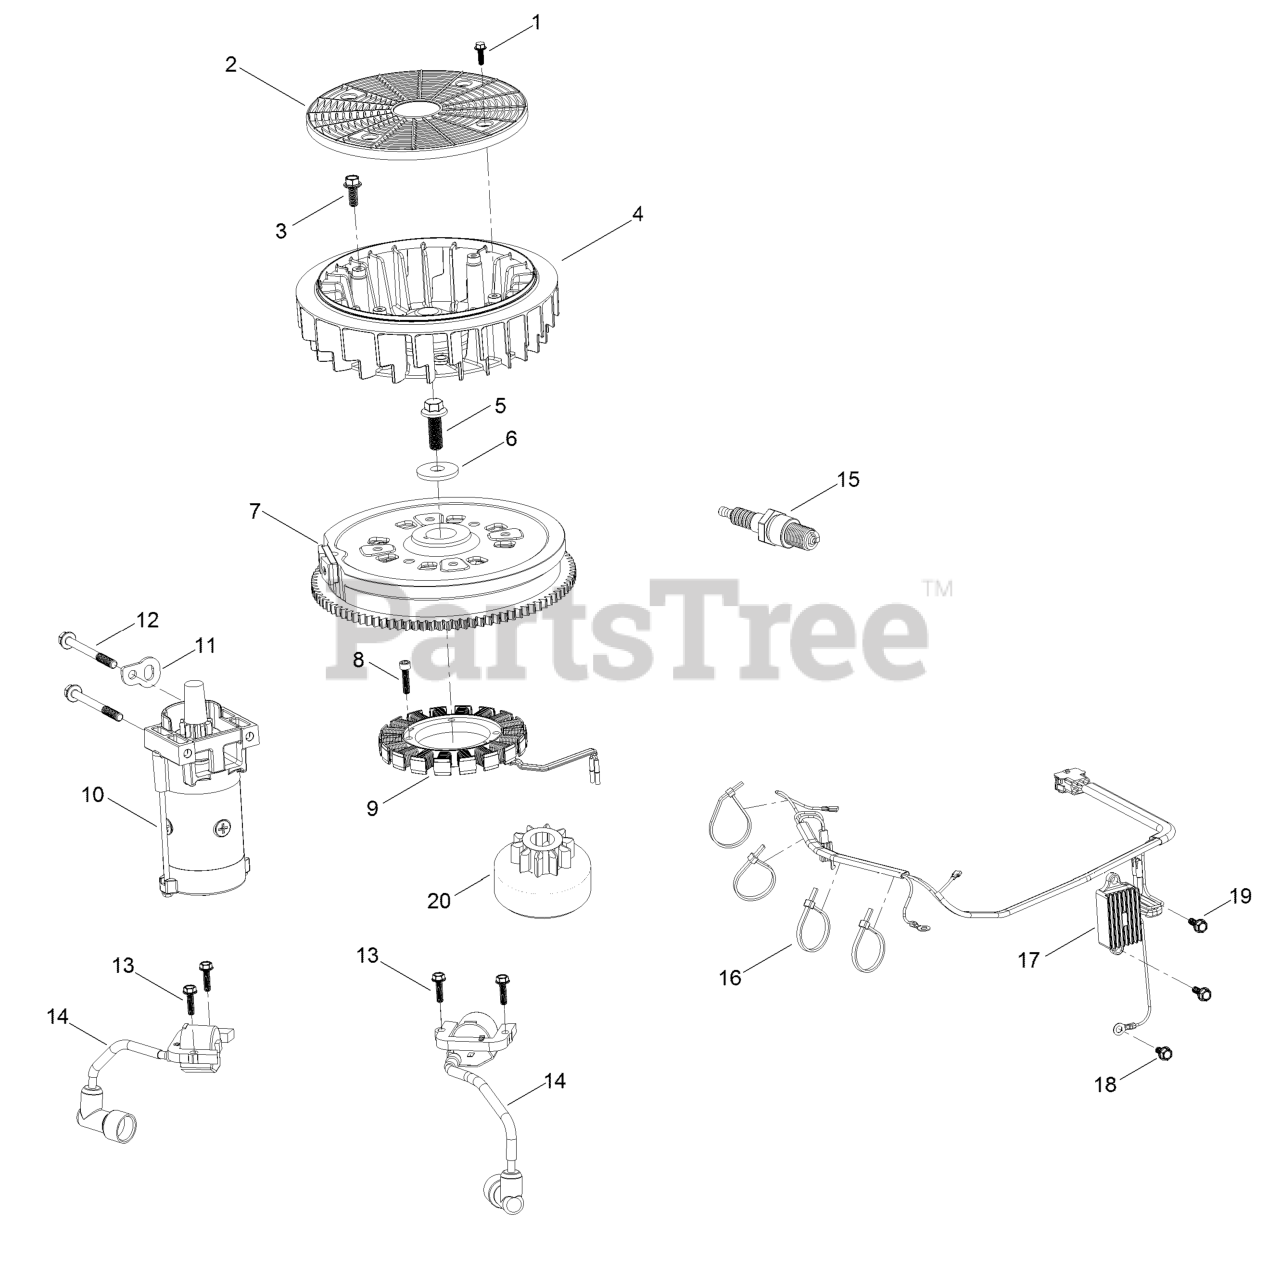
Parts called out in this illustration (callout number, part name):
1	SCREW-HWH
2	SCREEN-ROTATING
3	SCREW-HWH
4	FAN-COOLING
5	SCREW-HWH
6	WASHER-FLAT
7	FLYWHEEL
8	SCREW-HSH
11	BRACKET-LIFT
12	SCREW-HHF
13	BOLT-FLANGE
15	SPARK PLUG
16	TIE-ZIP
17	REGULATOR-VOLTAGE W/HARNE
18	SCREW-HHF
19	SCREW-HHF
20	PINION-STARTER
